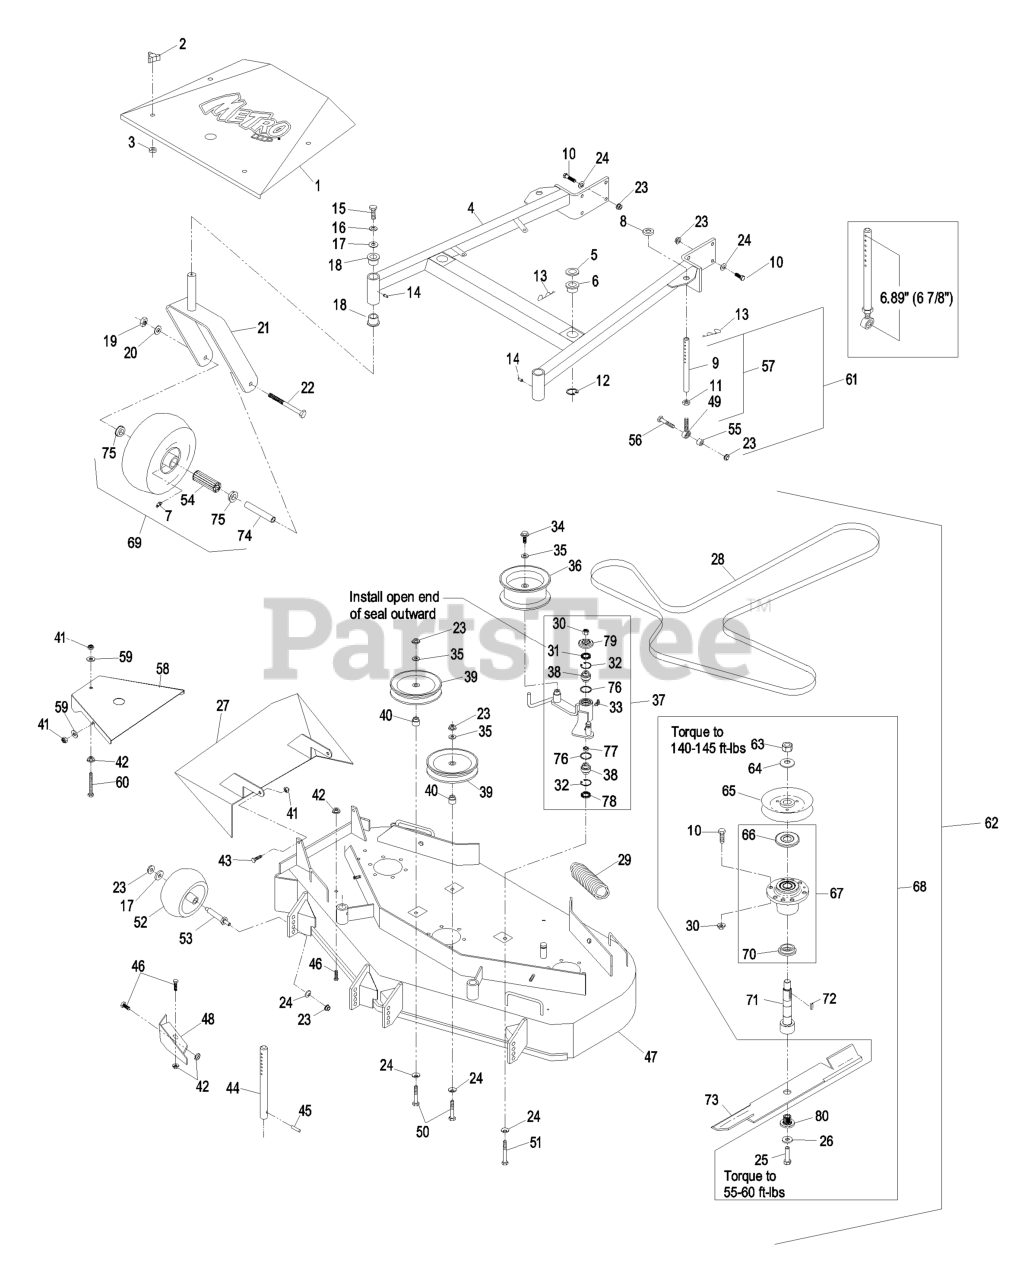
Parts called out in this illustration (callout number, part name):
1	SHIELD W/DECAL,MHP48
2	KNOB-3 PRONG
4	DECK SUPPORT W/BSHGS 48"
5	SPACER-DECK SUPPORT
6	BUSHING-DECK
7	FITTING-GREASE
9	LINK,SUPPORT
10	SCREW-HH
11	NUT-HEX
12	RING-RETAINING
13	PIN,HAIR COTTER
14	FITTING-GREASE
15	SCREW-HH
16	WASHER-LOCK
18	BEARING-FLANGED
19	NUT-HH
20	WASHER-LOCK
22	SCREW-HH
23	NUT-HHF, WHIZ
24	WASHER-BELLEVILLE
25	SCREW-HH
26	WASHER-SPRING
27	WLD,DISCHARGE CHUTE 36/48
28	BELT - V, B
30	NUT-LOCK, NI
31	SEAL-LIP, SINGLE
32	RING-SNAP
33	FITTING-GREASE, 90 DEG
34	SCREW-HHF
35	WASHER-FLAT
37	KIT, DECK IDLER TTHP48&52
38	BEARING-SPHERICAL
39	PULLEY-IDLER
40	BUSHING-IDLER
41	NUT-LOCK, NI
43	SCREW-HH
44	ROD,DECK SUPPORT
46	SCREW-HH
47	ASM,DECK W/DECALS TTHP/MH
49	BALLJOINT
50	SCREW-HH
51	SCREW-HH
52	ROLLER-SCALP, ANTI
54	BEARING
56	SCREW-HH
58	SHIELD,BELT
59	WASHER-FLAT
60	BOLT,TAP HH
62	Asm, Deck Complete
63	NUT-HH
65	SHEAVE,W/HUB 5.72
66	GUARD-BEARING, TOP
67	KIT, CUTTER HOUSING
68	ASM, CUTTER HSG
69	KIT, SP CASTER WHEEL REPL
70	SPACER-GUARD, BOTTOM
71	KIT, SPLINED SPINDLE 103-
72	KEY-RECTANGLE
75	BUSHING
78	SEAL-LIP, DOUBLE
79	GUARD-TOP
80	BUSHING,SPLINED
